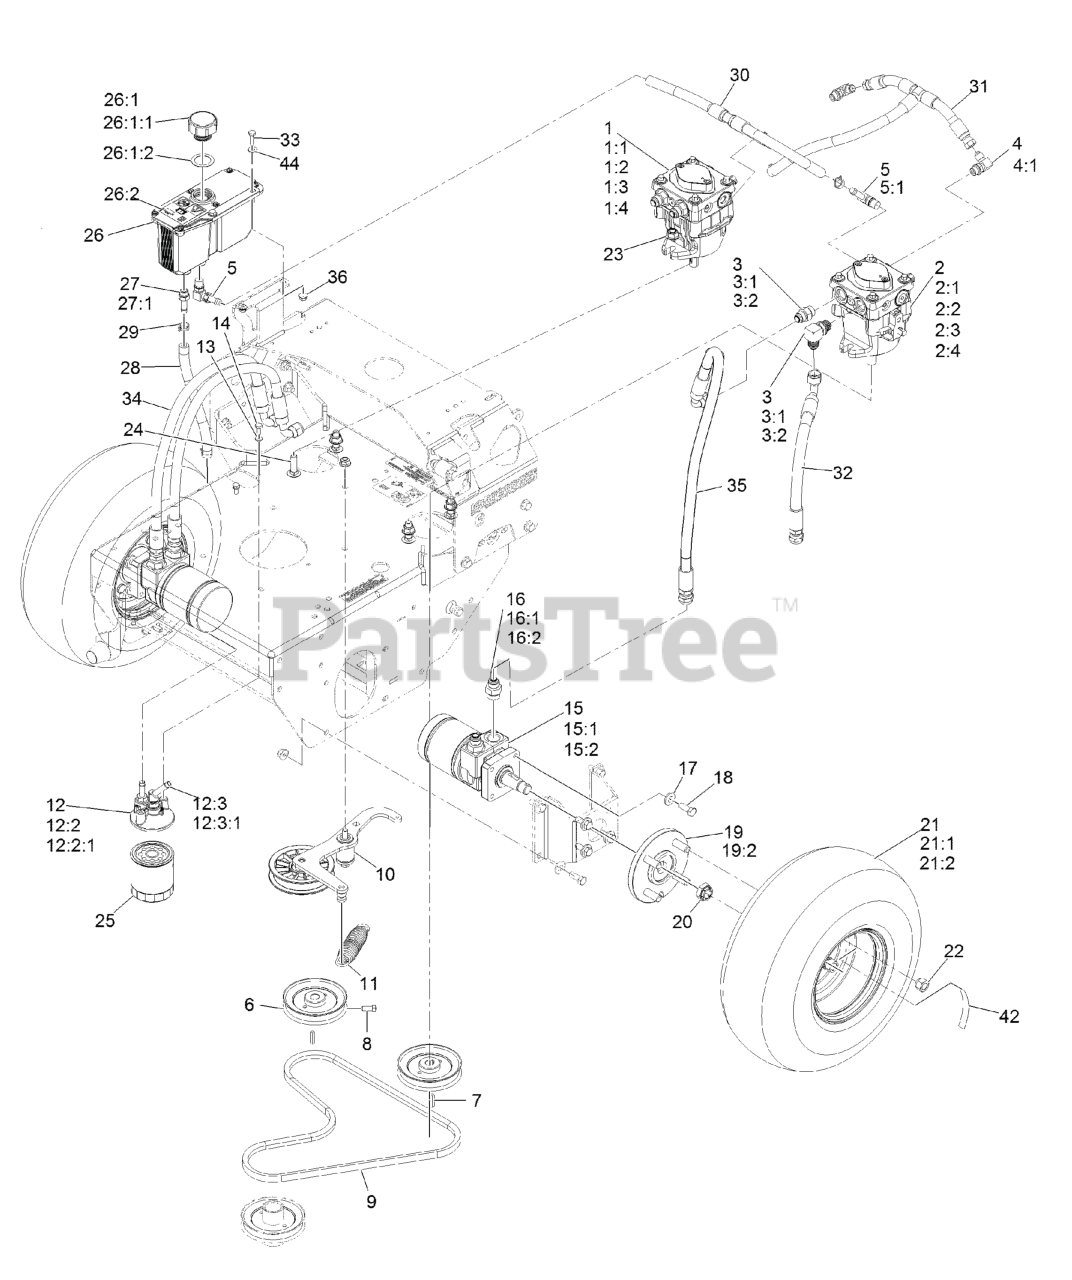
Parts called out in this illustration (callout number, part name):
1	RH HYD PUMP ASM
1:1	INPUT SHAFT KIT
1:2	BEARING-THRUST
1:3	CYLINDER BLOCK KIT
1:4	SEAL OVERHAUL KIT
2	LH HYD PUMP ASM
2:1	INPUT SHAFT KIT
2:2	BEARING-THRUST
2:3	CYLINDER BLOCK KIT
2:4	SEAL OVERHAUL KIT
3	FITTING-STRAIGHT
3	FITTING-90 DEG
4	FITTING-ELBOW, 90 DEG
4:1	O-RING
5	FITTING-ELBOW, 90
5:1	O-RING
6	SHEAVE ASM
8	SCREW-SET, SQH
9	BELT
10	ASM, PUMP IDLER
11	SPRING-EXTENSION
12	ASM, FILTER HEAD
12:2	ADAPTER-STRAIGHT
12:2:1	O-RING
12:3	FITTING-BARBED, 45 DEG
12:3:1	O-RING
13	WASHER-LOCK
14	SCREW-HH
15	HYD MOTOR ASM
15:1	SEAL KIT
15:2	BEARING AND SEAL KIT
16	FITTING-STRAIGHT
16:1	O-RING
17	WASHER-BELLEVILLE
18	SCREW-HH
19	WHEEL HUB ASM
19:2	STUD-WHEEL
20	NUT-LOCK
21	WHEEL AND TIRE ASM
21:1	TIRE-TURFMASTER
21:2	RIM-WHEEL
22	NUT-LUG
23	NUT-HF, NI
24	BOLT-CARR
25	FILTER-25 MICRON, BI-DIRE
26:1	Reservoir-HYD
26:1:1	Cap-Reservoir, HYD
26:1:2	GASKET-CAP
26:2	DECAL-WARNING
27	ADAPTER-STRAIGHT
27:1	O-RING
28	HOSE-CHARGE
29	CLAMP-HOSE
30	HOSE-CASE DRAIN
31	HOSE-CHARGE
32	ASM, HP HOSE
33	SCREW-HWH
34	HYD HOSE ASM
35	HYD HOSE ASM
42	DECAL-TORQUE WHEEL LUG-HU
